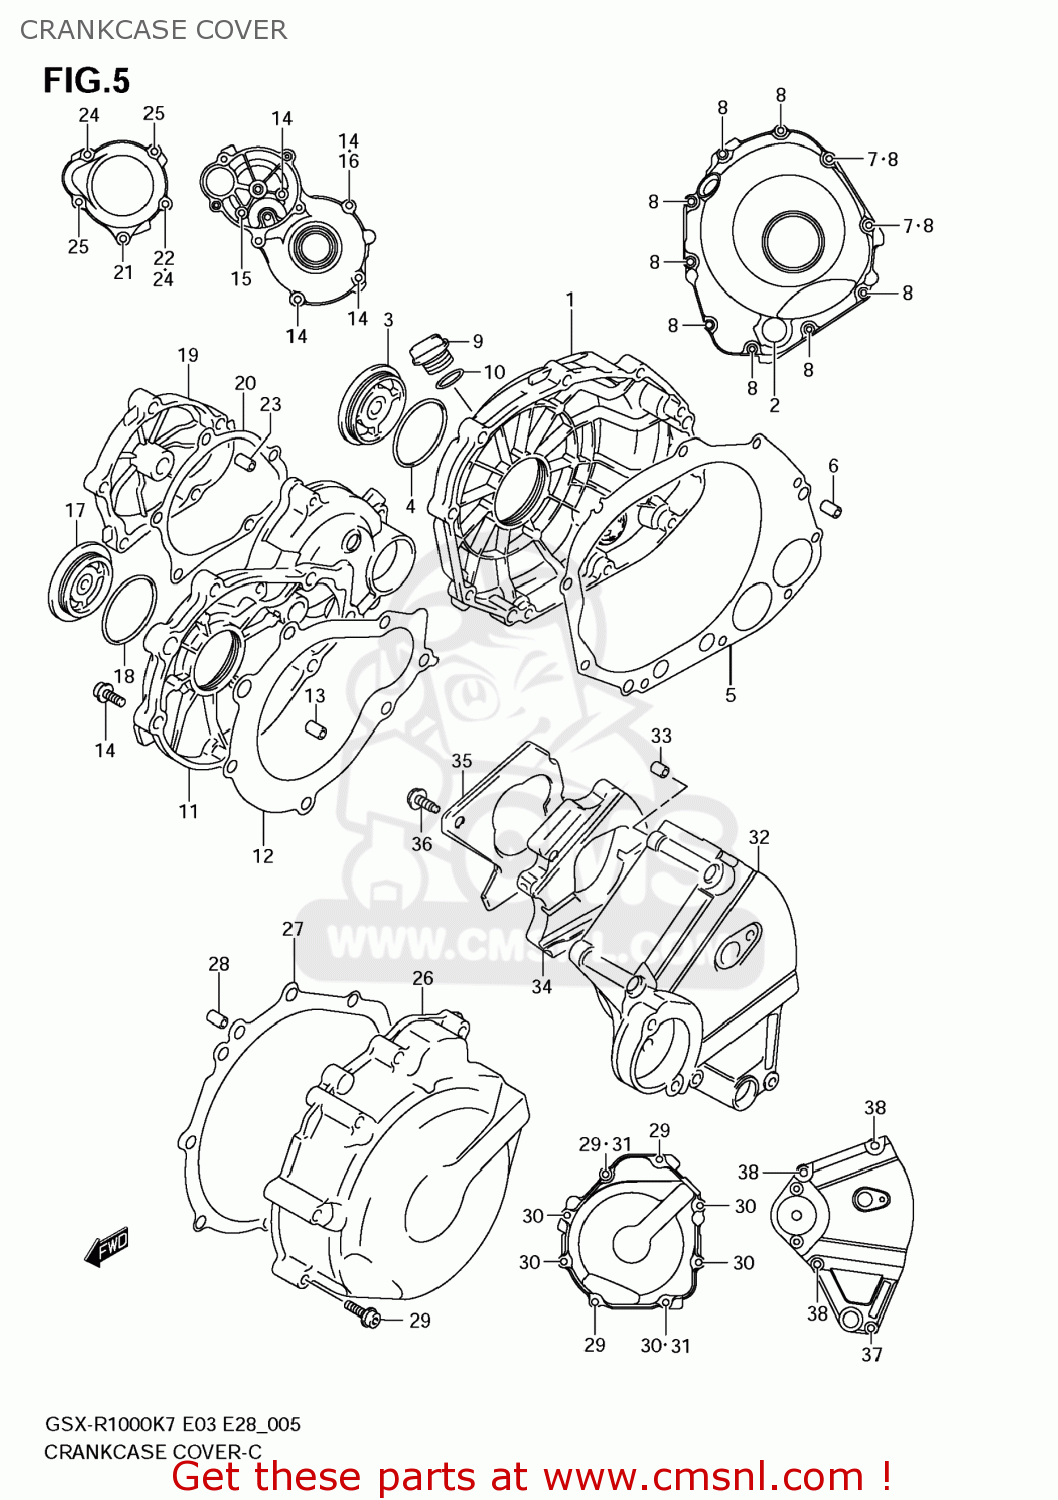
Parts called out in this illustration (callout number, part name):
1	COVER,CLUTCH
2	LENS,OIL LEVEL CHECK
3	CAP,CLUTCH RELEASE ADJUST
4	O RING(D:2.4,ID:52.6)
5	GASKET,CL COVE (NAS)
6	PIN
7	GASKET(5.8X13X1.2) (NAS)
8	BOLT
9	PLUG,ENGINE OIL FILLER
10	O RING(D:3.1,ID:16.8)
11	COVER,STARTER CLUTCH
12	GASKET,STARTER CLUTCH COVER
13	PIN
14	BOLT
15	BOLT
16	GASKET(5.8X13X1.2) (NAS)
17	PLUG
18	O RING(D:3.1,ID:32.7)
19	CAP,STRAINER IDLE GEAR
20	GASKET,START IDLE GEAR CAP (NAS)
21	BOLT
22	GASKET(5.8X13X1.2) (NAS)
23	PIN
24	BOLT
25	BOLT
26	COVER,MAGNETO
27	GASKET,MAGNETO COVER (NAS)
28	PIN
29	BOLT
30	BOLT
31	GASKET(5.8X13X1.2) (NAS)
32	COVER,ENGINE SPROCKET
33	PIN
34	DAMPER,ENGINE SPROCKET COVER
35	PLATE,ENGINE SPROCKET COVER
36	BOLT(6X12)
37	BOLT
38	BOLT
